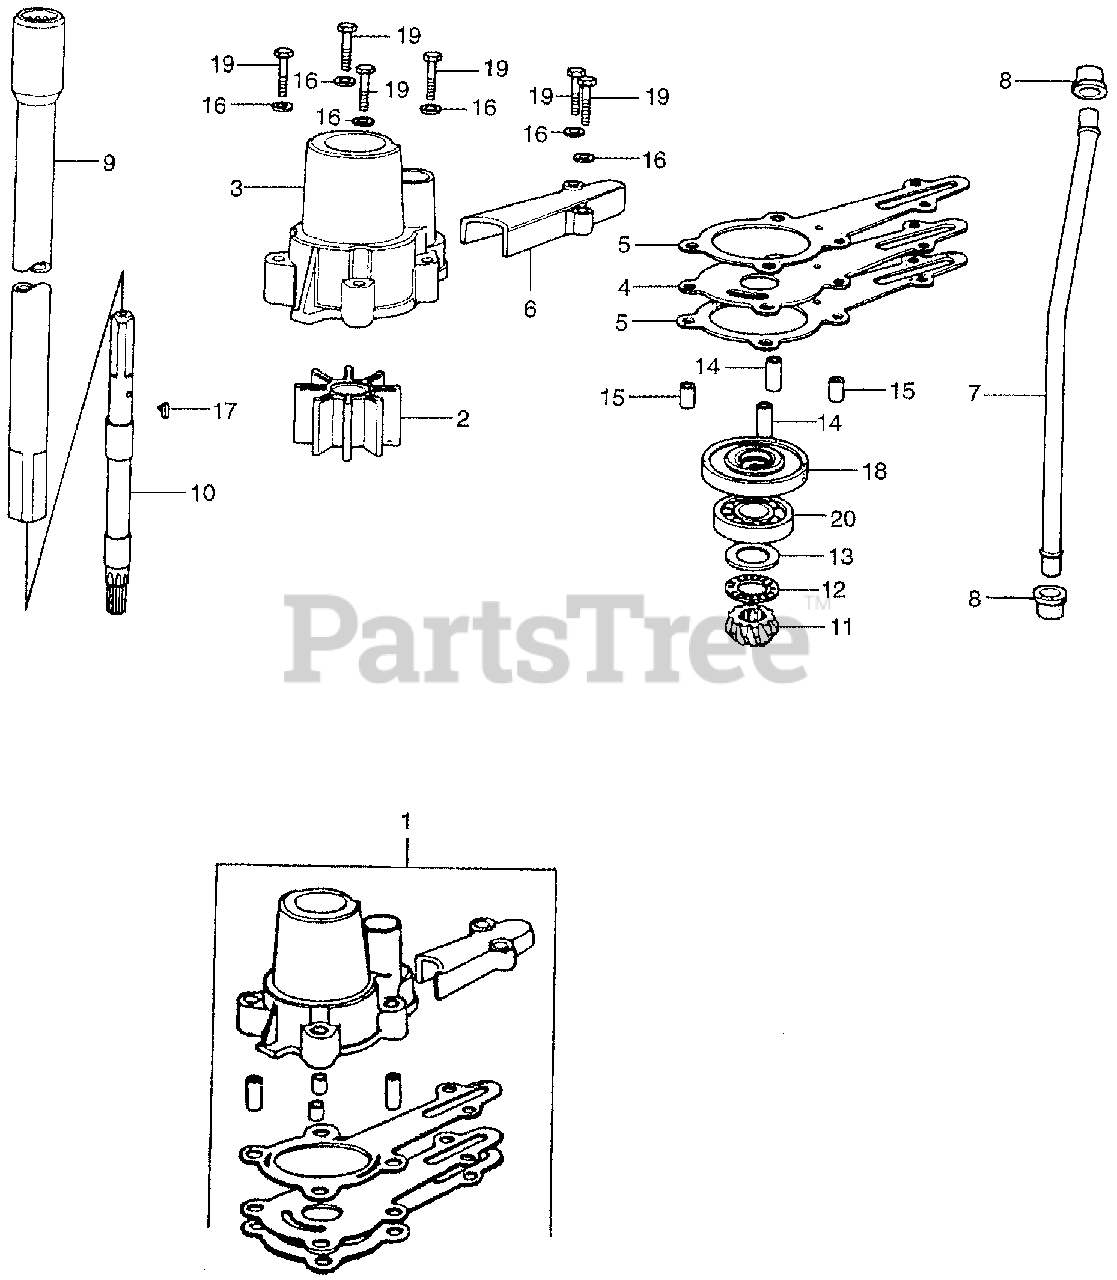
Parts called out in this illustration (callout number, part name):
1	HOUSING, IMPELLER (NOT AVAILABLE)
2	IMPELLER, PUMP
3	HOUSING, IMPELLER (NOT AVAILABLE)
4	COVER, IMPELLER (NOT AVAILABLE)
5	GASKET, IMPELLER
6	HOLDER, IMPELLER COVER (NOT AVAILABLE)
7	TUBE, WATER (NOT AVAILABLE)
8	RING, SEAL
9	SHAFT, VERTICAL (NOT AVAILABLE)
9	SHAFT, VERTICAL
10	SHAFT, PINION (NOT AVAILABLE)
11	PINION, BEVEL
12	BEARING, THRUST (15MM)
13	WASHER A, THRUST BEARING (2.00MM)
13	WASHER B, THRUST BEARING (2.05MM)
13	WASHER C, THRUST BEARING (2.10MM)
14	COLLAR A, DISTANCE
15	COLLAR B, DISTANCE (NOT AVAILABLE)
16	WASHER, PLAIN (6MM)
17	KEY, IMPELLER
18	SEAL, WATER (15MM) (NOK)
19	BOLT, HEX. (6X28)
20	BEARING, RADIAL BALL (6302)
